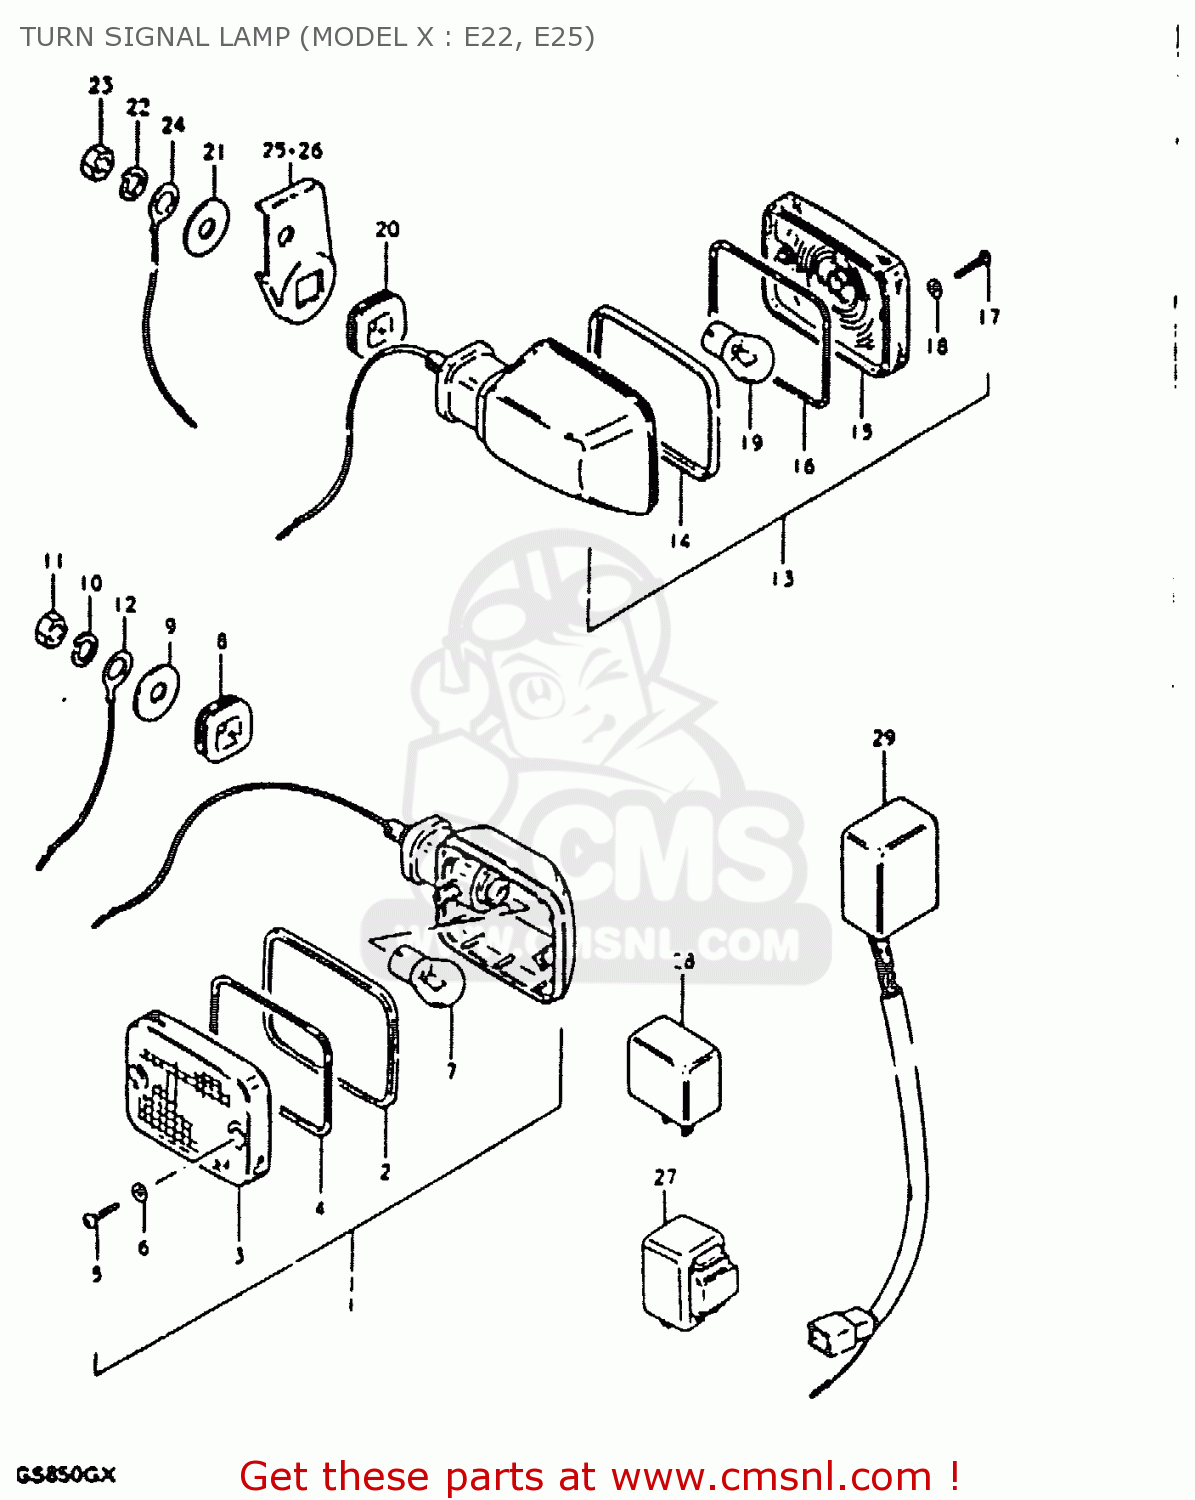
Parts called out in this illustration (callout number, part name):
1	LAMP, REAR TURN SIGNAL
2	RIM
3	LENS
4	GASKET (NAS)
5	SCREW
6	GASKET (NAS)
7	BULB(12V21W)
8	CUSHION
9	WASHER (10.5X30X2.3)
10	LOCK WASHER
11	NUT
12	LEAD WIRE,EARTH
13	LAMP, REAR TURN SIGNAL
14	RIM
15	LENS
16	GASKET (NAS)
17	SCREW
18	GASKET (NAS)
19	BULB(12V21W)
20	CUSHION
21	WASHER (10.5X30X2.3)
22	LOCK WASHER
23	NUT
24	LEAD WIRE,EARTH
25	BRACKET,RR TURNSIGNAL LAMP,R
26	BRACKET,RR TURNSIGNAL LAMP,L
27	RELAY, TURN SIGNAL
28	RELAY ASSY,TURNSIGNAL
29	UNIT,TURN SIGNAL CONTROL
